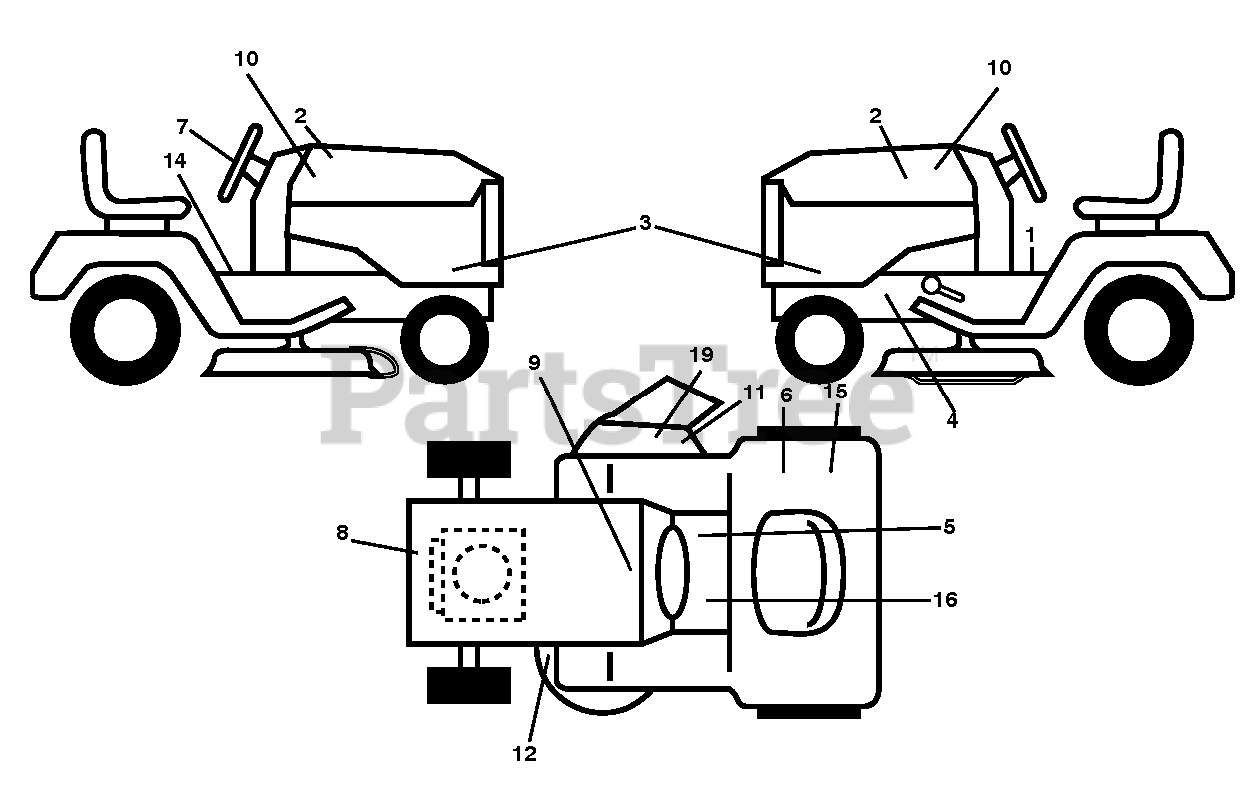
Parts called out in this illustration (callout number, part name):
1	DECAL
2	DECAL.HOOD.HUSQVARNA.INTERNATI
5	DECAL PARK BRAKE
6	DECAL 80 DBA
7	DECAL.STEERING.HUSQ.BLUE
8	DECAL
9	DECAL BTRY SYMBOLS
11	DECAL, DEFLECT WARNING
12	DECAL V BELT SCHEMATIC
14	LABEL
15	DECAL
16	DECAL
19	DECAL.INTERNATIONL.CUTFINGER
